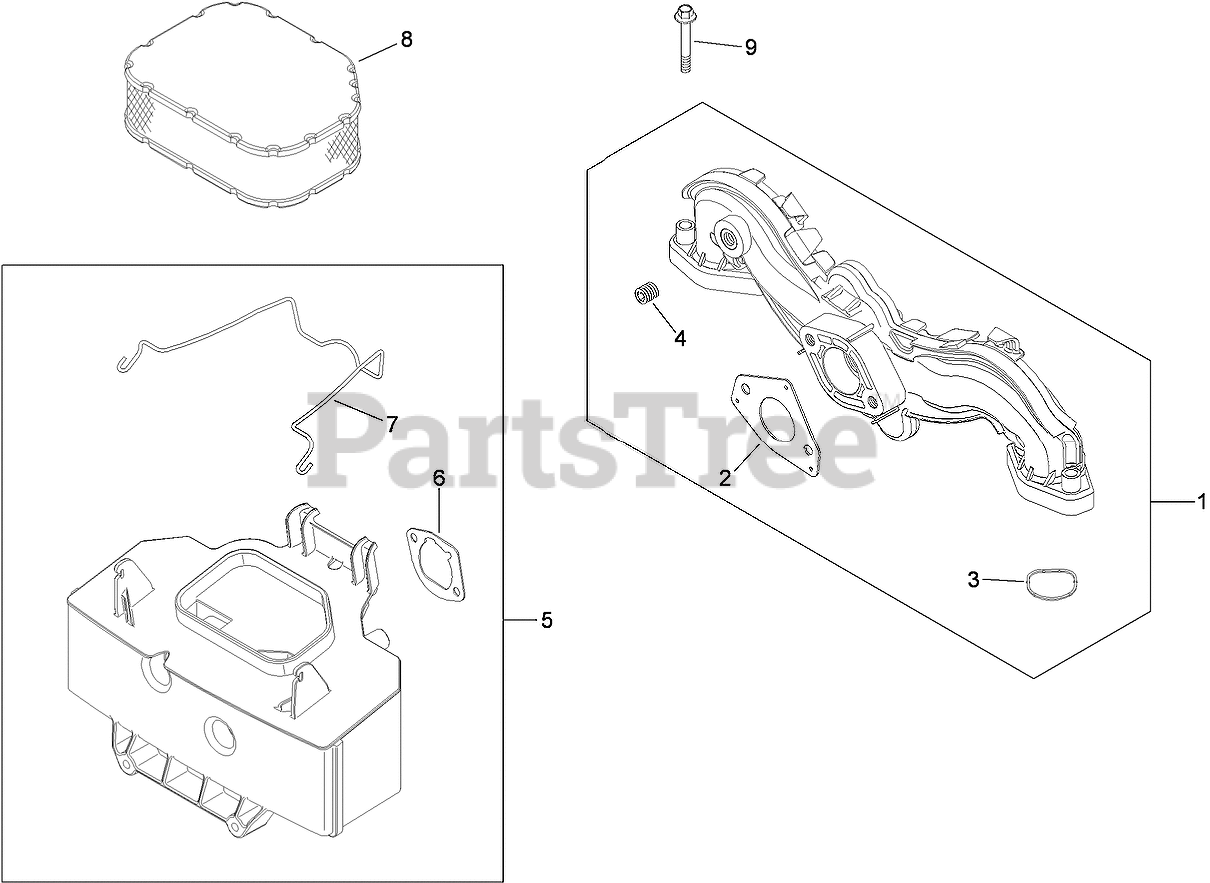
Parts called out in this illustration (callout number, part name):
1	INTAKE MANIFOLD ASM (INCLUDES 2-4)
2	GASKET-CARBURETOR
3	O-RING (INTAKE PORT)
4	PLUG-PIPE, COUNTERSUNK (1/8)
5	AIR CLEANER BASE KIT (INCLUDES 6, 7)
6	GASKET-BASE, AIR CLEANER
7	LATCH-ELEMENT, AIR CLEANER
8	ELEMENT-FILTER, AIR
9	SCREW-FLANGE (M6X1.0X40)
